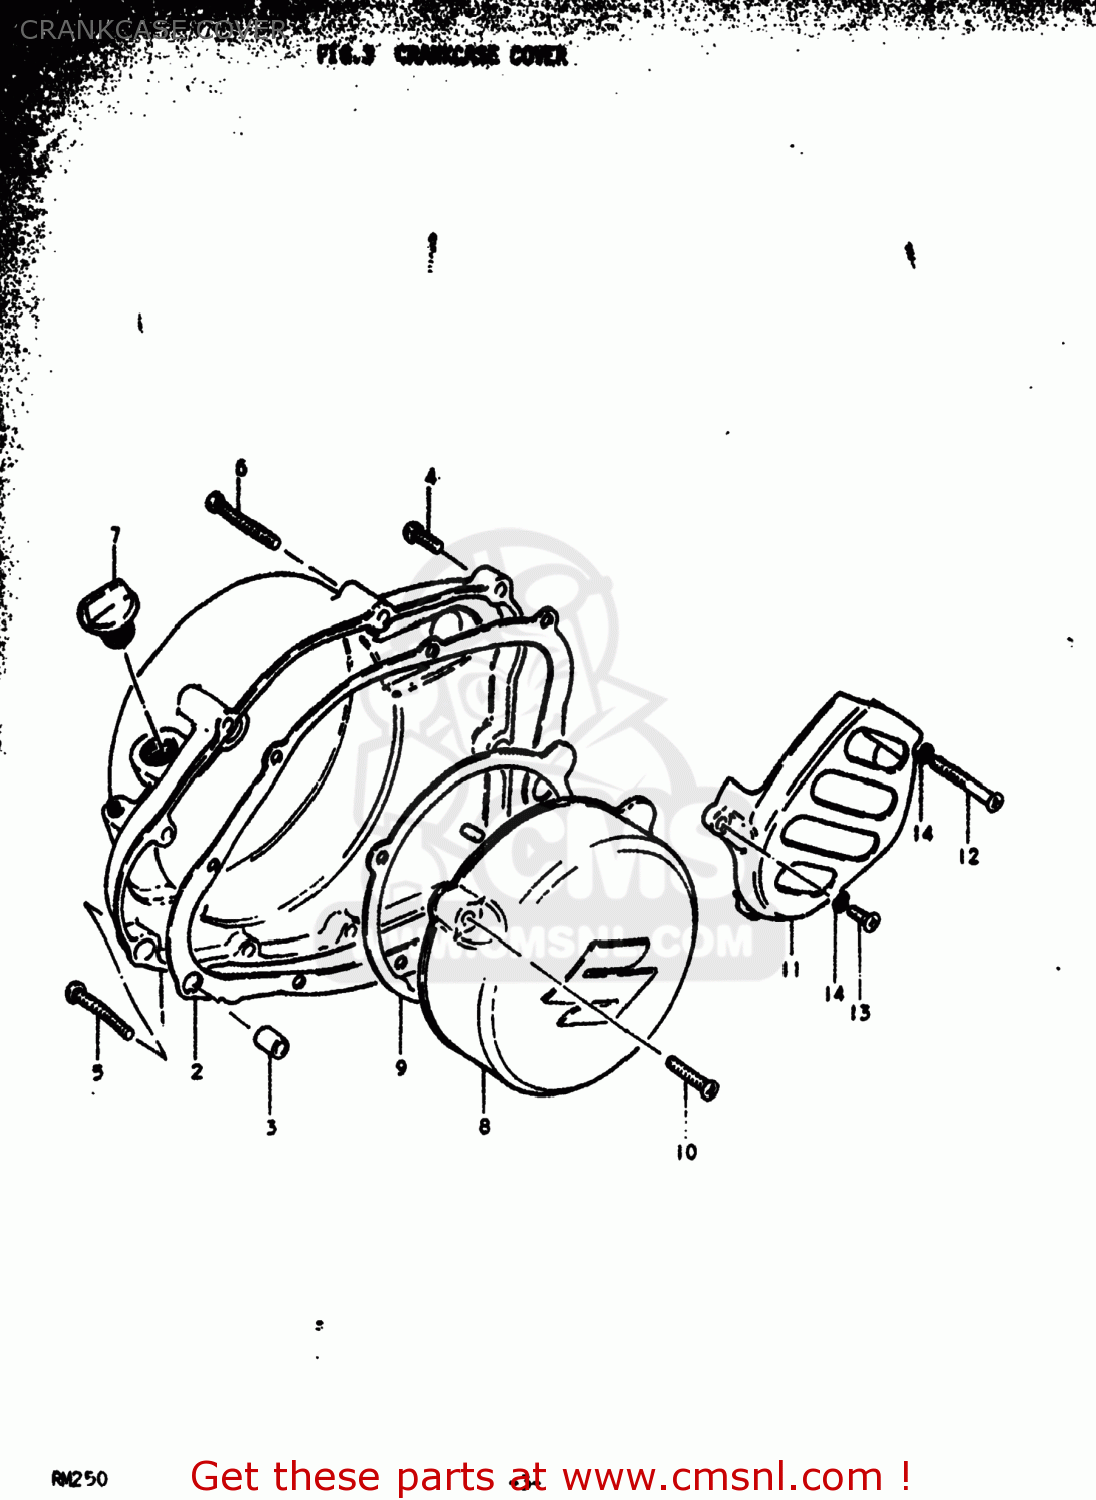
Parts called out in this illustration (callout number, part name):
1	COVER,CLUTCH
2	GASKET,CLUTCH COVER (MCA)
3	PIN
4	SCREW
5	SCREW
6	SCREW (6X45)
7	PLUG,OIL FILTER
8	COVER,MAGNETO
9	GASKET,MAGNETO COVER (MCA)
10	SCREW
11	COVER,SPROCKET
12	SCREW
13	SCREW
14	LOCK WASHER
